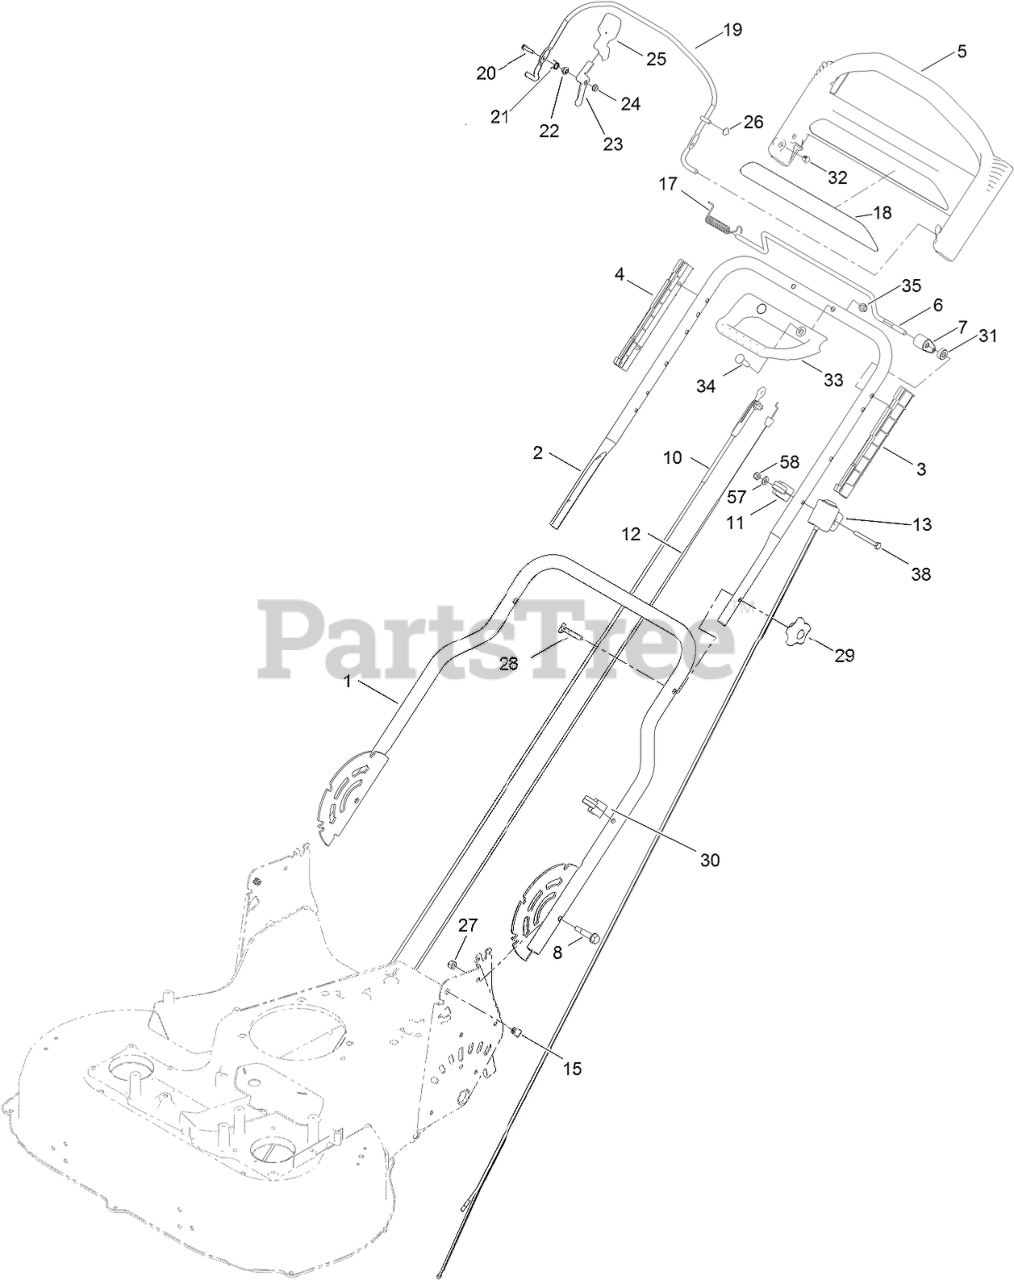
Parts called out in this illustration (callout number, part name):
1	HANDLE-LOWER
2	HANDLE-UPPER
3	GUIDE-LH
4	GUIDE-RH
5	HANDLE-CONTROL
6	BAR-CONTROL, TRACTION
7	LEVER-TRACTION
8	BOLT-SHOULDER, HHF
10	CABLE-BRAKE
11	ANCHOR-CABLE
12	CABLE-TRACTION
13	SWITCH HOUSING ASM
15	PLUG-SQUARE
17	SPRING-TORSION
18	DECAL-HANDLE
19	BAIL-BRAKE
20	SCREW-HWH
21	SPRING-TORSION
22	SPACER
24	NUT-HEX FLANGE
26	NUT-SPEED
27	NUT-HEX
28	SCREW-HANDLE
29	KNOB-HANDLE
30	GUIDE-CABLE
31	SPACER
32	PLUG-DOME
33	HANDLE-ASSIST, TRACTION
34	BOLT-CARRIAGE
35	NUT-ACORN
38	SCREW-HH
57	WASHER-FLAT
58	NUT-HEX
